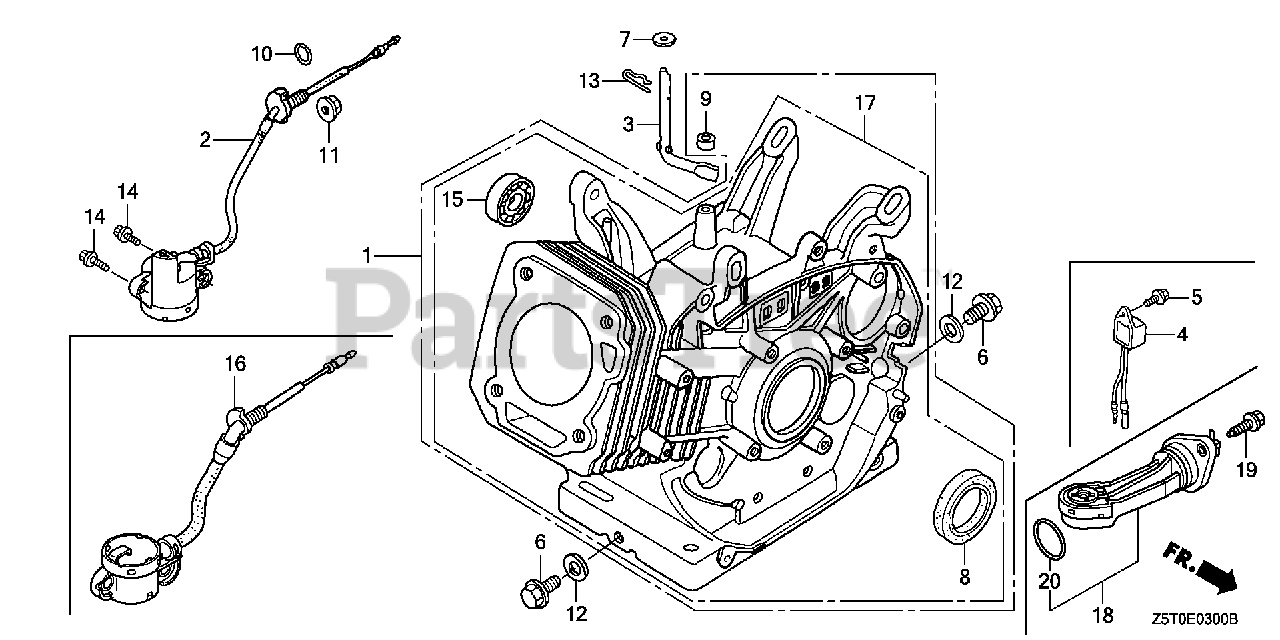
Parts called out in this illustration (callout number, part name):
6	BOLT, DRAIN PLUG (12X15)
8	OIL SEAL (35X52X8) (NOK)
12	WASHER, DRAIN PLUG (12MM)
15	BEARING, RADIAL BALL (6202)
17	CYLINDER ASSY. (SELF STARTER+ALERT)
18	SWITCH ASSY., OIL LEVEL
19	BOLT, FLANGE (6X16) (CT200)
20	O-RING (37.9X2.4)
